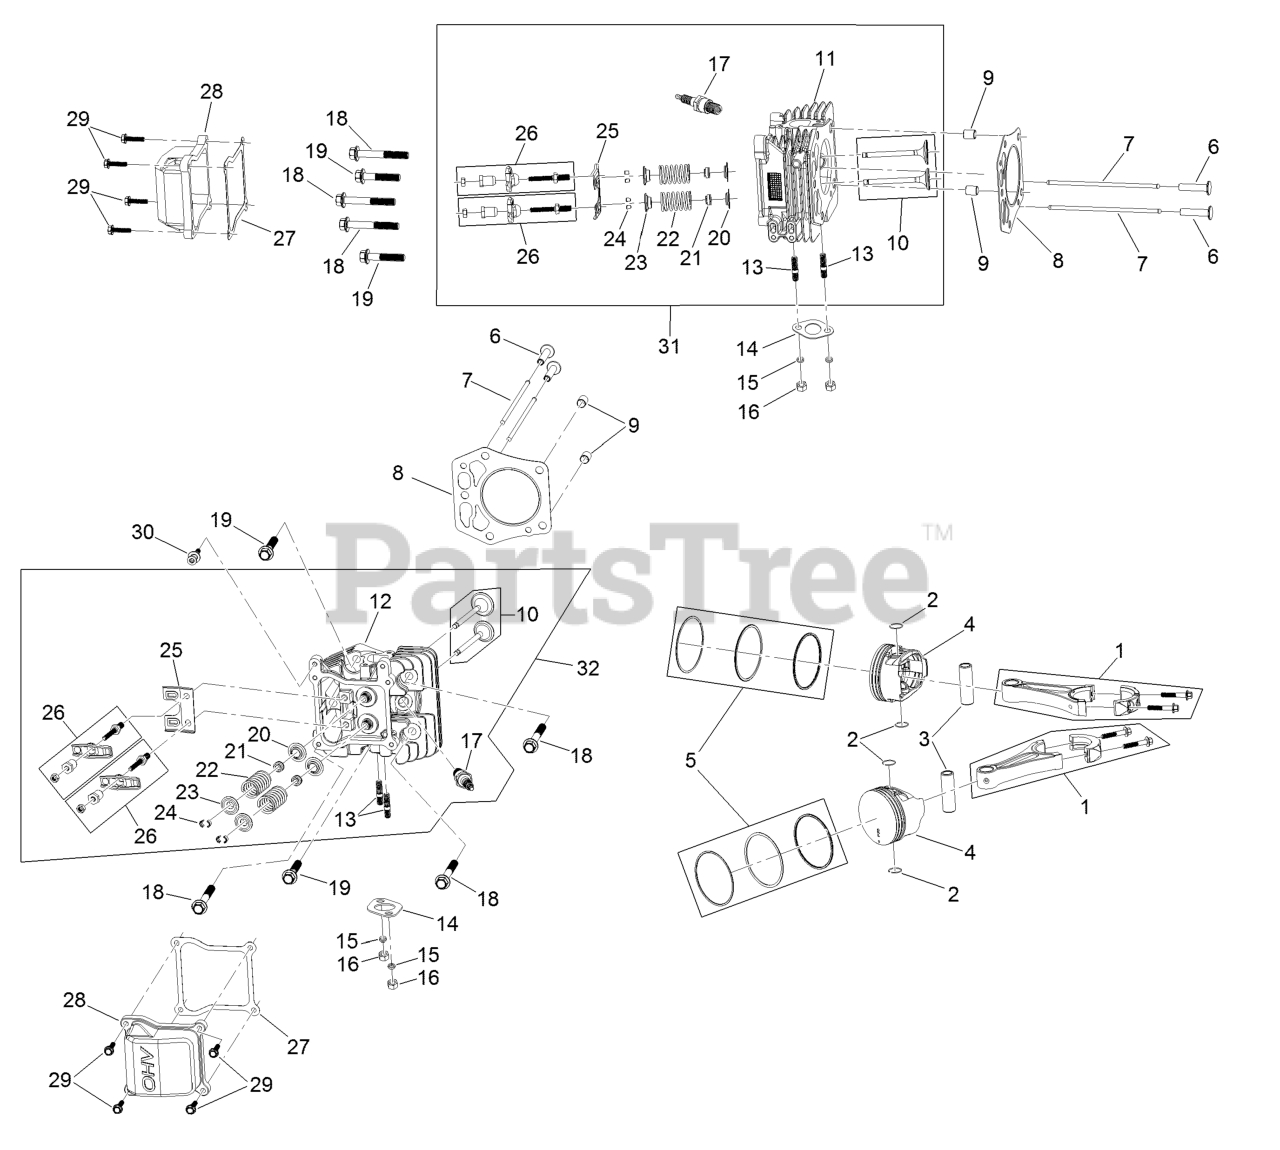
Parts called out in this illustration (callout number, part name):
1	Connecting Rod ASM
2	Clip-Pin, Piston
3	Pin-Piston
5	Piston Ring Set
6	Lifter-Valve
7	Rod-Push
8	Gasket-Head, Cylinder
9	Pin-Dowel
10	Valve Set
11	Head-Cylinder, Right
12	Head-Cylinder, Left
13	Stud-Exhaust
14	Gasket-Exhaust
15	Washer-Lock, Split
17	Spark Plug
18	Screw-HWH
19	Screw-HWH
20	Seat-Spring, Valve
21	Seal-Stem, Valve
22	Spring-Valve
23	Retainer-Spring, Valve
24	Keeper-Valve
25	Plate-Guide, Push Rod
26	Rocker Arm ASM
27	Gasket-Valve Cover
28	Cover-Valve
29	Screw-HHF
30	Screw-Shoulder, HH
31	Right Head ASM
32	Left Head ASM
